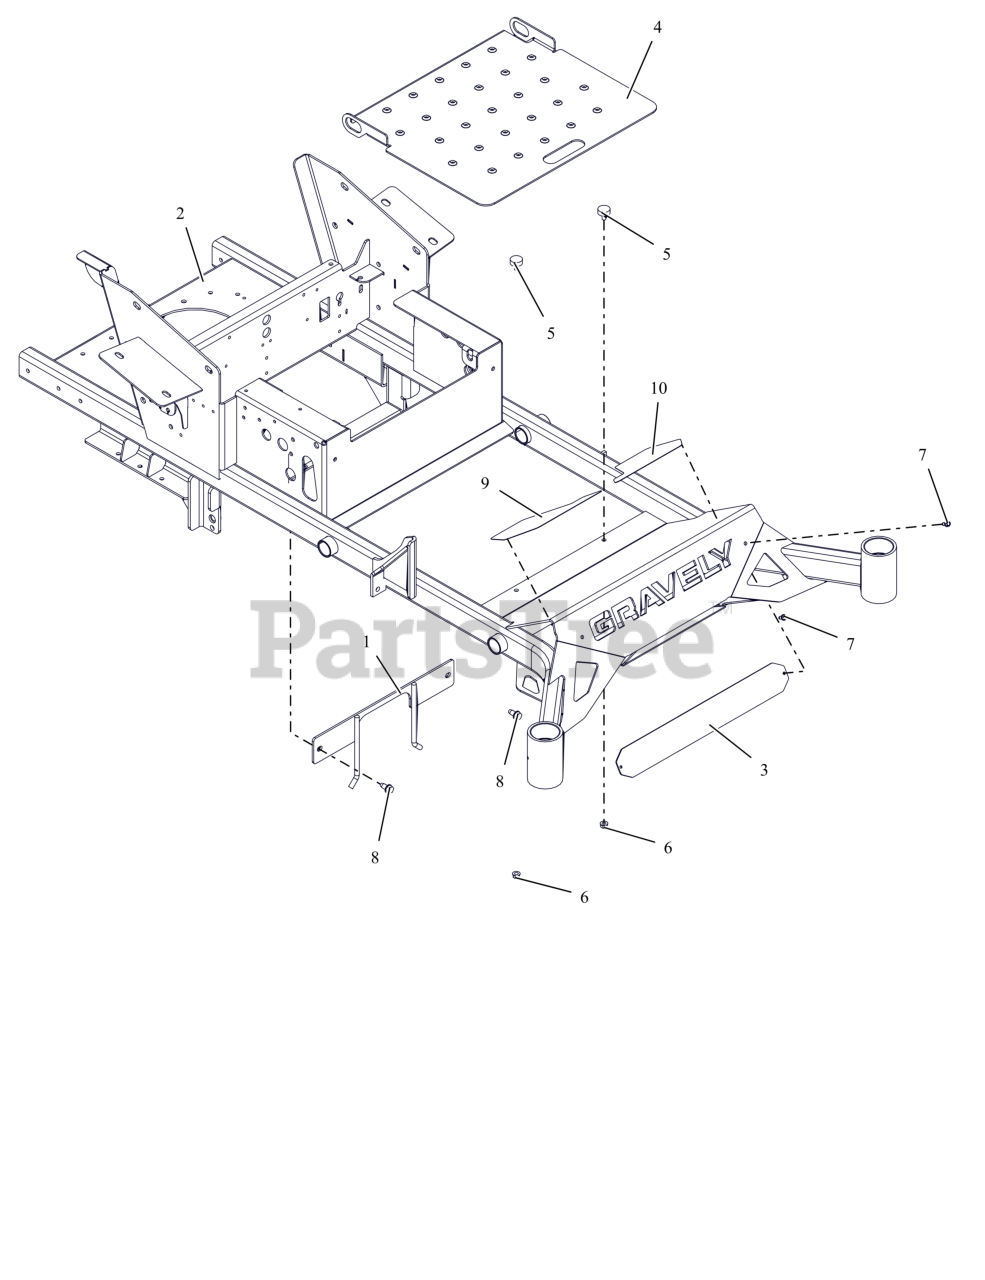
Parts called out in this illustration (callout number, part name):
1	PTO BELT FINGER WLDMT - BLK
2	PT/100 60" FRAME W/SAFETY DECL
3	BUMPER LOGO BACKING PLATE -BLK
4	PT/100 FOOT PLT W/SAFETY DECAL
5	BUMPER, RUBBER
6	NUT,SPNLK-FLG .31-18 G5 ZCC
7	SCR-TAP .25-20X.50 HWH ZCC
8	SCR,TAP .375-16X.75 HWH TR ZCC
9	GRIP, RH FOOT PLATE
10	GRIP, LH FOOT PLATE
